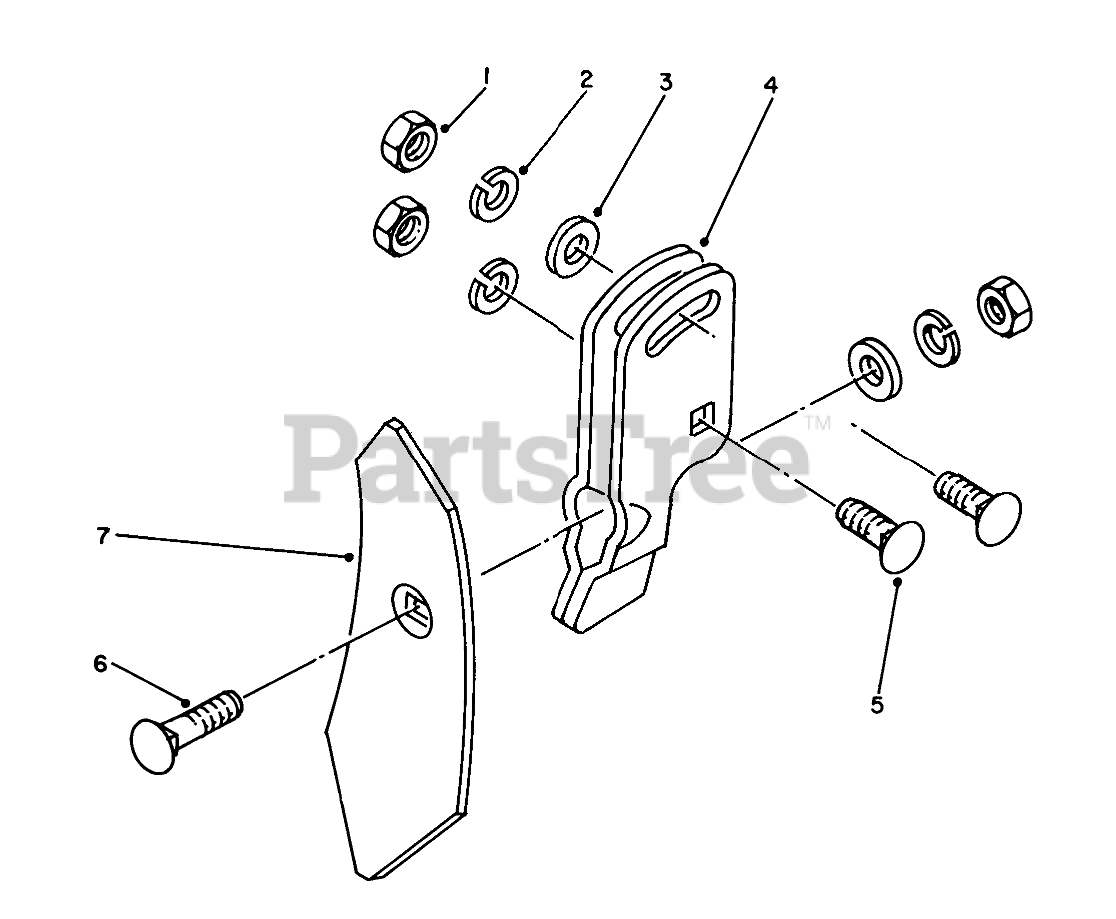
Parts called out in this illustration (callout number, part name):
1	NUT-HEX
2	WASHER-LOCK
3	WASHER-FLAT
4	Holder
5	BOLT-CARR
6	Plow Bolt
7	Shovel
